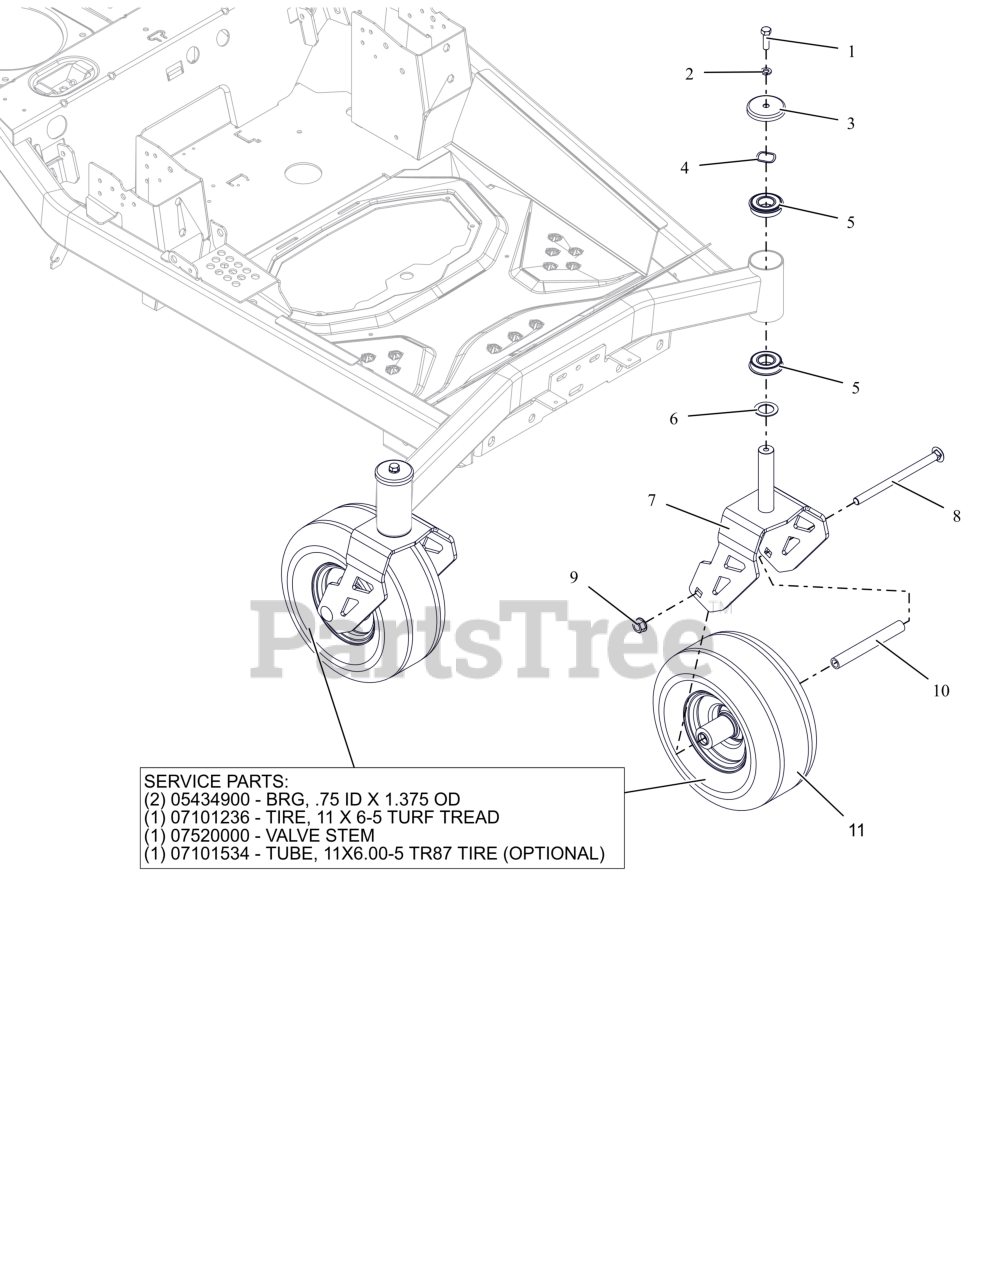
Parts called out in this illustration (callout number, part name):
1	BLT- HEX .38-16X1.25 G5 ZB500
2	WSHR-LK-REG .375X.094 ZB500
3	SHIELD, AXLE BEARING
4	WSHR-WAVE 1.0X1.25X.028 .145FH
5	BEARING, BALL -2.000 OD X 1.000 ID X .5625 W/RING
6	WSHR-HRD-THRS 1.007X1.542X.062
7	WLDMT, CASTER FORK (ORANGE)
8	BLT-RHSN .50-13X7.50 G5 ZCC NS
9	NUT-LK-CTR-FLG .500-13 GG ZCC
10	SPACER, FRONT WHEEL (WIDE 6.0)
11	ASM- WHL/TIRE 11 X 6.00-5
11	BRG-BALL .752X1.380X.500
11	LAWN TIRE FRONT, 11/6.00-5 SMOOTH
11	VALVE STEM ASS'Y
11	TUBE- 11X6.00-5 TR87 TIRE
